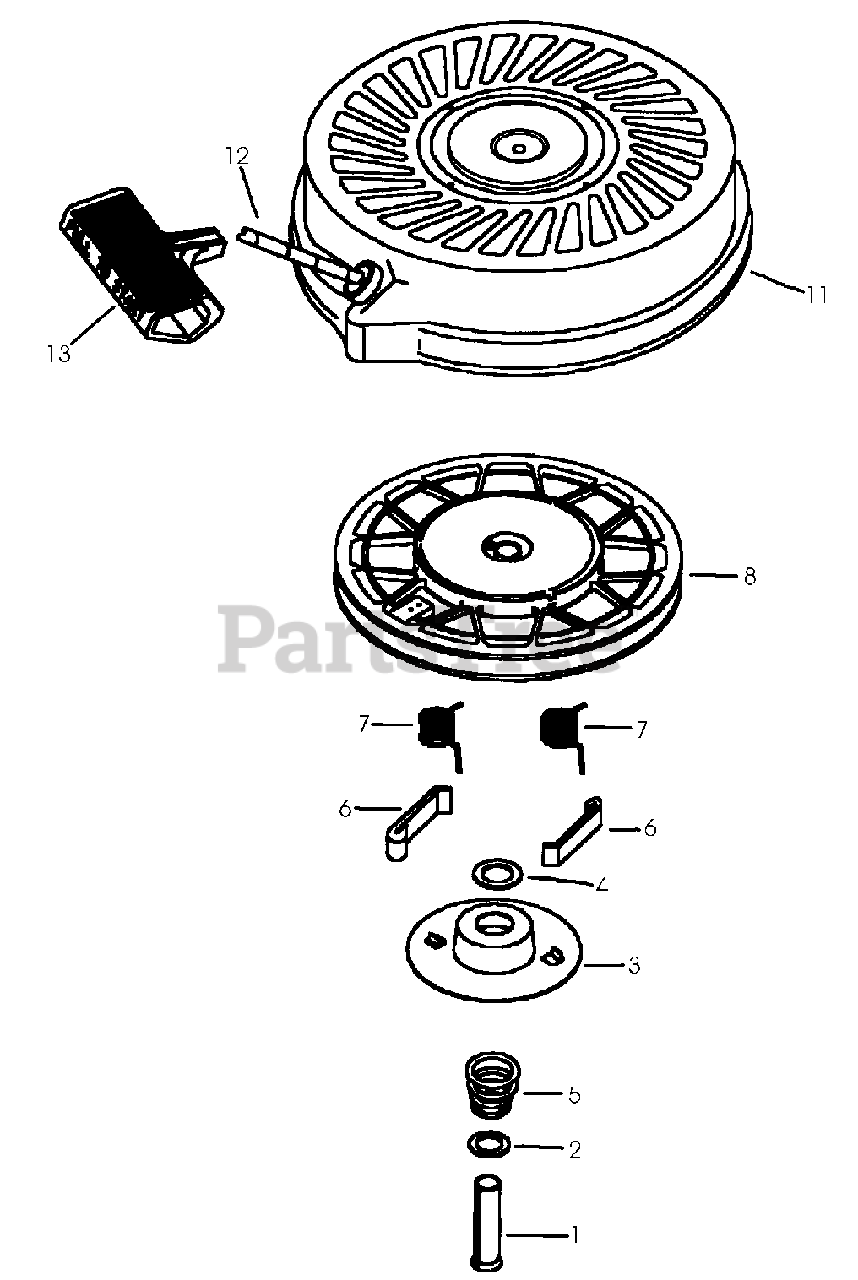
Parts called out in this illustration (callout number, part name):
1	Spring Pin (Incl. 4)
2	Washer
3	Retainer
4	Washer
5	Brake Spring
6	Dog-Starter
7	Dog Spring
8	Pulley & Spring-Rewind
11	Housing Ass-y-Starter
12	Rope Starter
13	Handle-Starter
